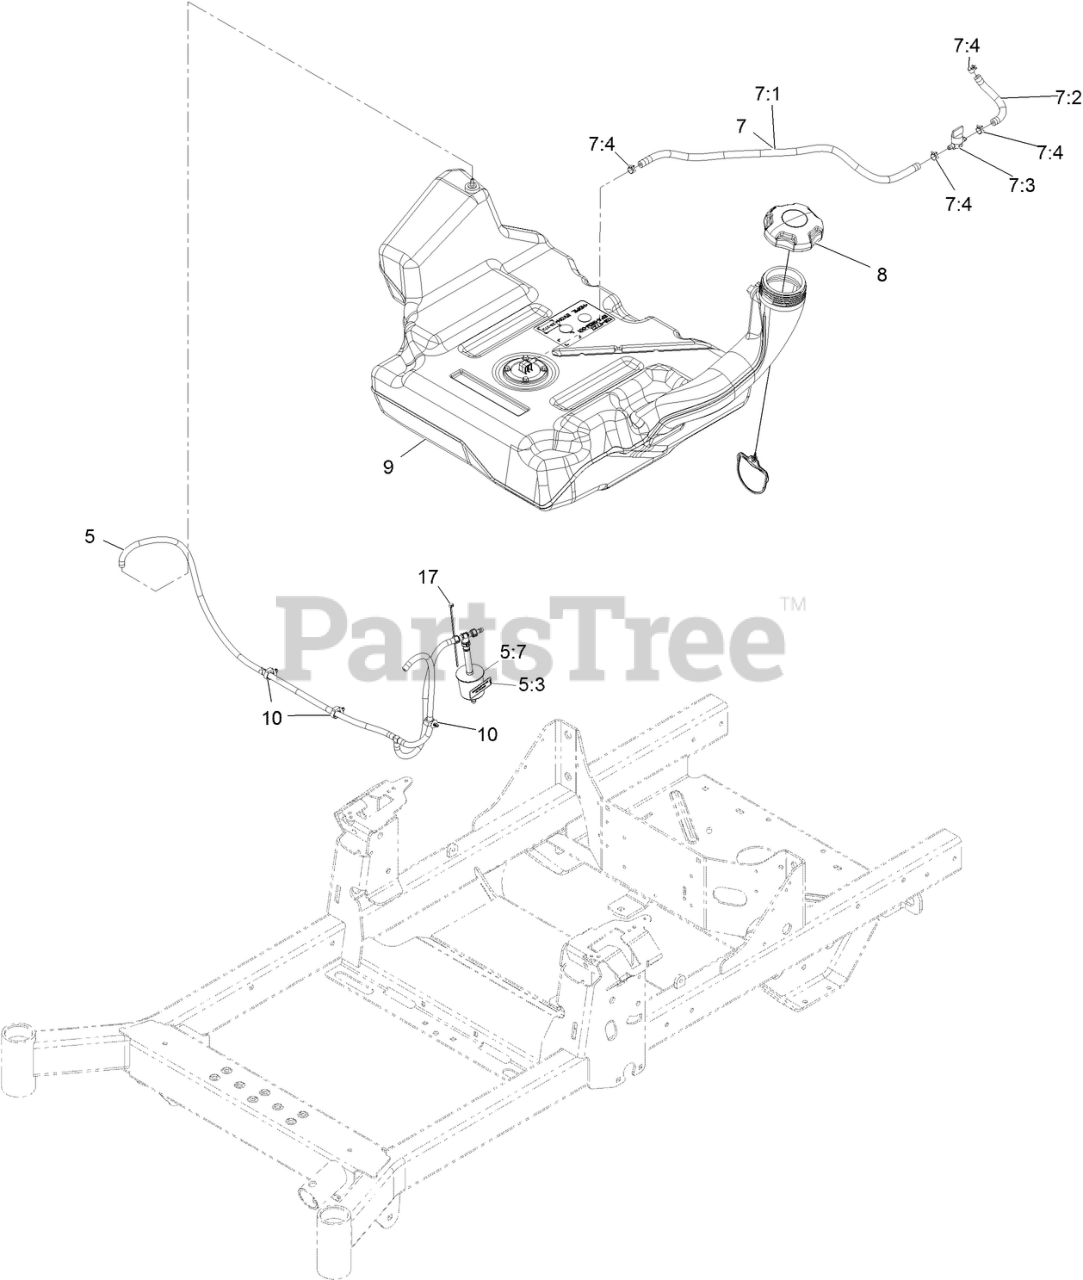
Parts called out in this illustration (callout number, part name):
5	VENT HOSE ASM
5:3	DECAL-FILTER, EMISSIONS
5:7	FILTER-FUEL
7	FUEL HOSE ASM
7:1	HOSE-FUEL
7:2	HOSE-FUEL
7:3	VALVE-FUEL
7:4	CLAMP-HOSE
8	CAP-FUEL, RATCHETING
9	TANK-FUEL
17	TIE-CABLE
